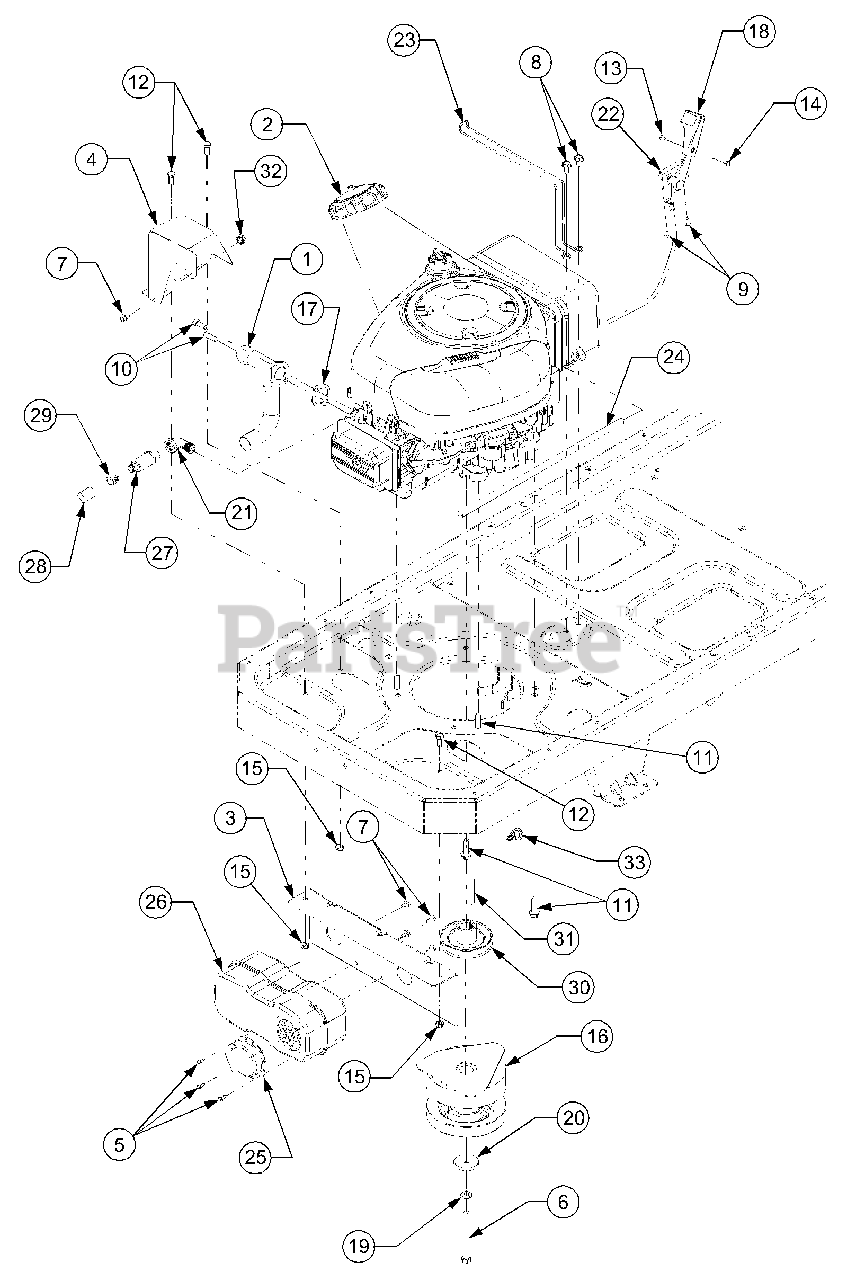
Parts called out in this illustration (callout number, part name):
1	Tube, Exhaust
2	Tank, Fuel, 3.0 Gal.
3	Bracket, Muffler Mounting
4	Shield, Muffler Tube Heat
5	Screw, Hex Wash. Hd. Tapp #8-18 x .5
6	Screw, Hex Cap, 7/16-20 x 4.0 GR5
7	Screw, Hex Wash. Hd. Tapp 1/4-20 x .5
8	Screw, Hex Wash. Hd. Tapp 5/16-12 x .75
9	Screw, Hex Wash. Hd. Tapp #12-16 x .5
10	Screw, Socket Hd. 5/16-18 x .75
11	Screw, Hex Wash. Hd. Tapp 3/8-16 x 1.25
12	Screw, Hex Cap, 5/16-18 x .75 GR5
13	Screw, Truss Hd. Mach. #8-32 x .375
14	Nut, Hex, #8-32
15	Nut, Hex Insert Lock, 5/16-18 GR5
16	Clutch Assembly, Electric PTO
17	Gasket, Exhaust (272293)
18	Knob, Throttle Control
19	Washer, Lock, 7/16
20	Washer, Flat, .438 x 1.75 x .25
21	Fitting, Elbow
22	Cable, Throttle, 39.0 Lg
23	Wire, Tank Mounting
24	Hose, Fuel Line
25	Deflector, Muffler
26	Muffler
27	Valve, Oil Drain
28	Hose, Oil Drain Extension
29	Cap, Oil Drain Valve
30	Pulley, Drive, 3.25 Dia.
31	Key, Square, 1/4 x 2.25
32	Nut, Hex Sems, 1/4-20
33	Clip, Cable Retainer
